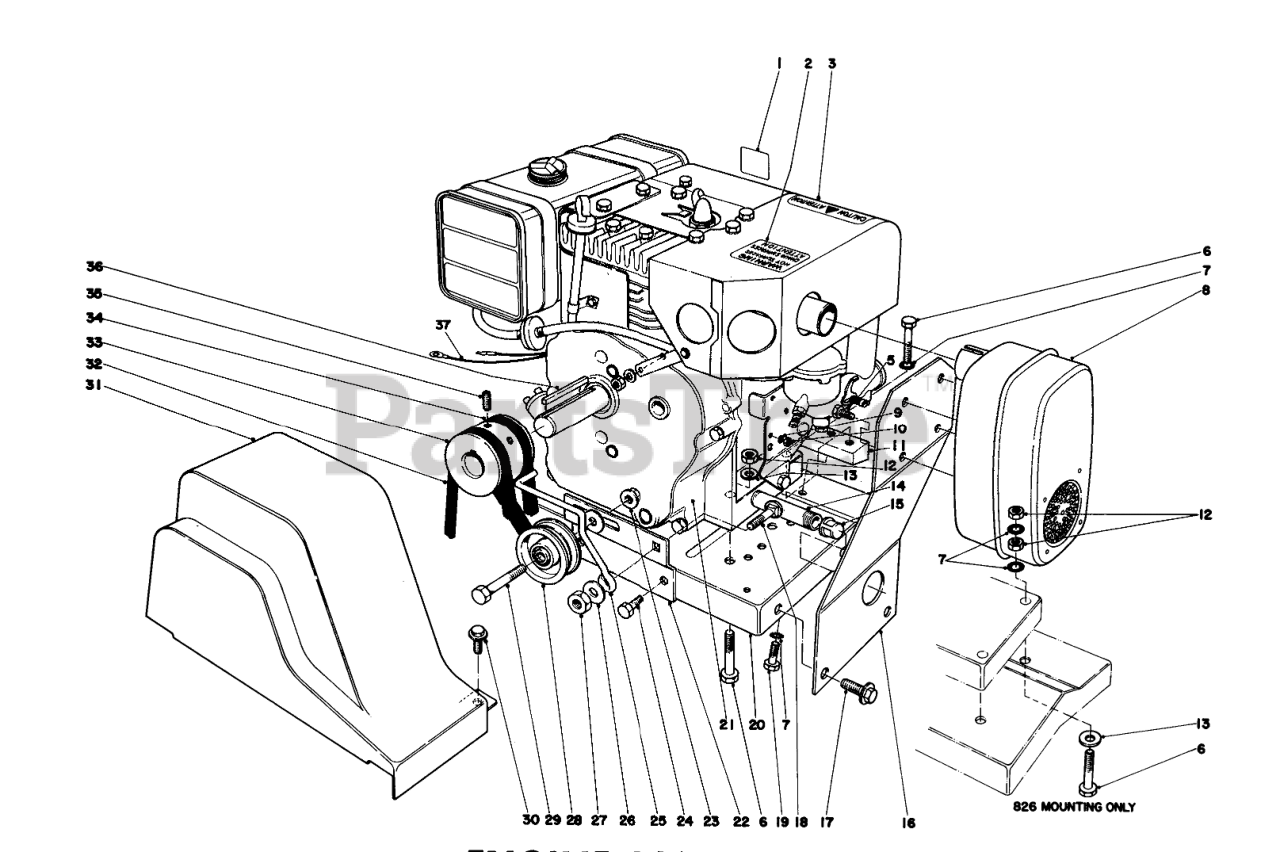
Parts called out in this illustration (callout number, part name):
1	CHOKE DECAL
2	Decal Hot Surface Warning
3	CAUTION DECAL
5	1/4-20 X 1/2 SEMS MS
6	SCREW-HH
7	WASHER-LOCK, INTERNAL
8	Muffler
9	WASHER-LOCK/INT
10	NUT-LOCK
11	Block Engine Mounting
12	NUT-LOCK, NI
13	WASHER-PLAIN
14	NIPPLE-PIPE
15	CAP-PIPE
16	Muffler Mounting Bracket
17	SCREW-HH
18	SCREW-CARR
19	SCREW-HH
20	Base-Engine
21	Engine
22	Belt Idler Bracket
23	NUT-HHF, WHIZ
24	SCREW-HHFTF
25	BELT GUIDE
26	WASHER-FLAT
27	NUT-HEX
28	PULLEY B
29	SCREW-HH
30	SCREW-HWH
31	BELT GUARD
32	V-BELT
33	ENGINE PULLEY
34	V-BELT
35	Screw-Set
